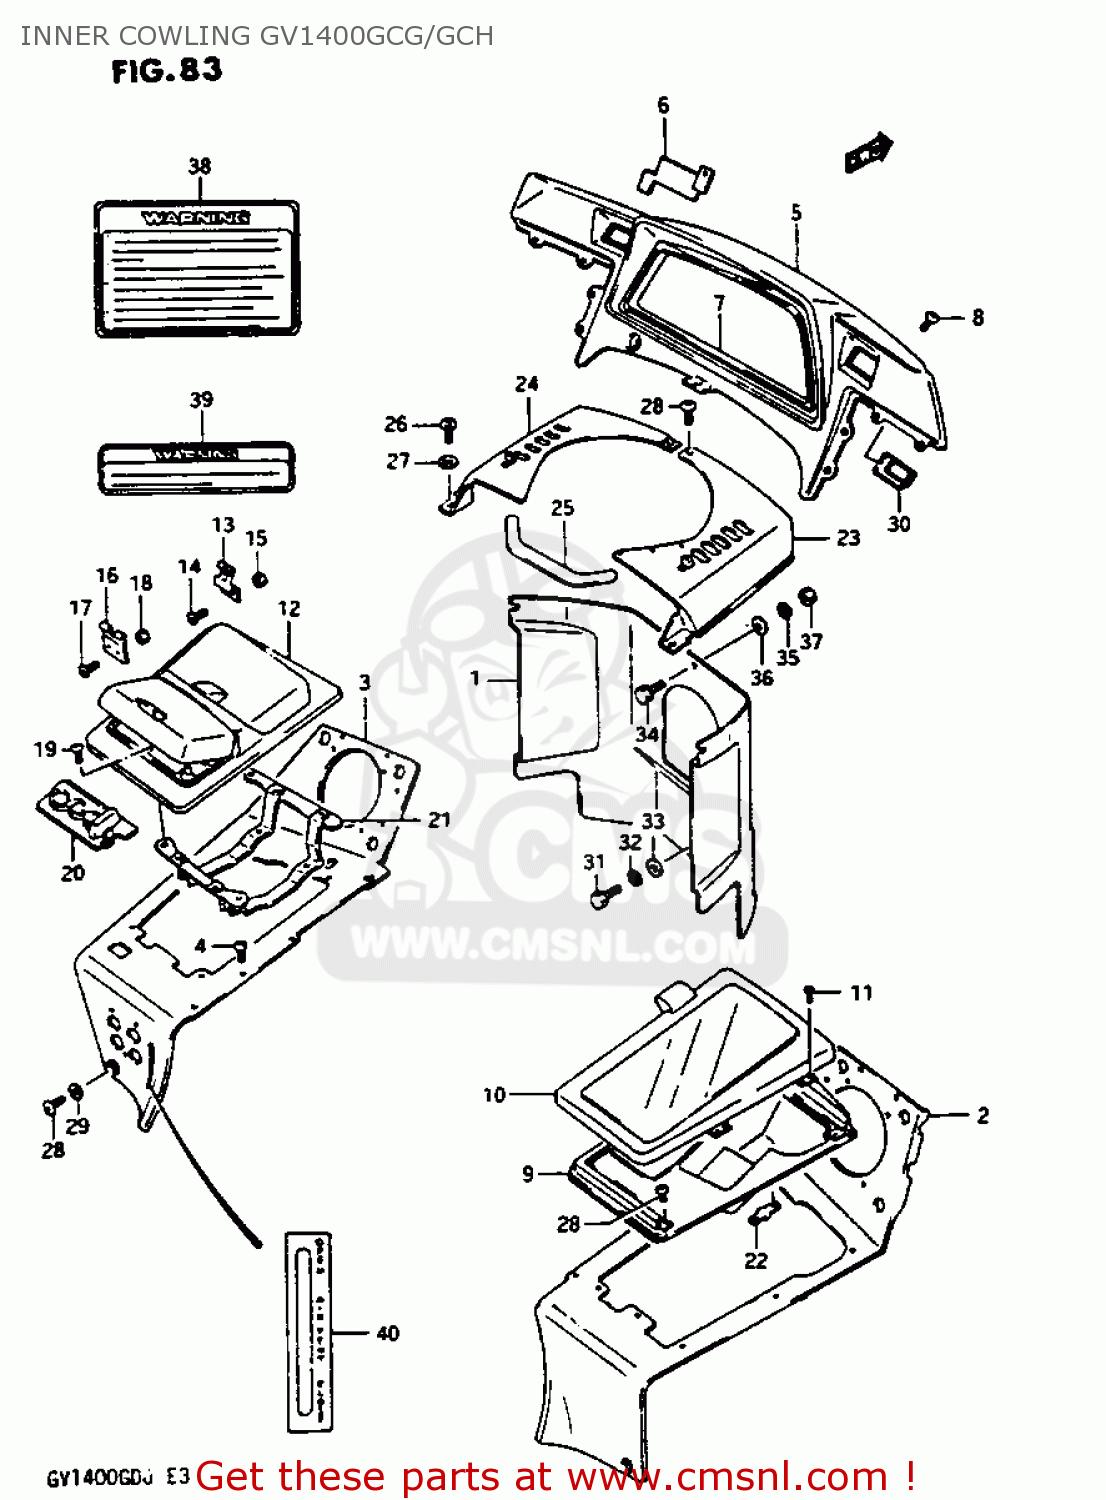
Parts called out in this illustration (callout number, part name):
1	COVER,COWLING,INNER
2	PANEL,COWLING,R
3	PANEL,COWLING LH
4	SCREW
5	COVER ASSY,METER
6	COVER,METER COVER HOLE
7	MOLDING,METER COVER
8	SCREW 5X10
9	BOX COMP,COWLING PANEL,RIGHT
10	CASE SET,COWL PANEL BOX MAP
11	SCREW
12	BOX COMP,COWLING PANEL,LEFT
13	HINGE
14	SCREW
15	NUT
16	HINGE,COWLING BOX LID NO
17	SCREW
18	NUT
19	SCREW 5X10
20	CASE,COIN HOLDER
21	BRACKET COMP,COWLING BOX
22	PLATE,PANEL BOX BASE
23	COVER ASSY,FRAME HEAD,R(BLACK)
24	COVER ASSY,FRAME HEAD,L(BLACK)
25	SEAL,FRAME HEAD
26	SCREW
27	WASHER,5.5X12X
28	SCREW
29	WASHER (4.3X13X0.80)
30	CAP,RADIO IND
31	BOLT
32	LOCK WASHER
33	WASHER,5.5X12X
34	BOLT
35	LOCK WASHER
36	WASHER,5.5X12X
37	NUT
38	LABEL (WARNING)
39	LABEL (WARNING COVER CO
40	EMBLEM,PANEL COWLING,LEFT
